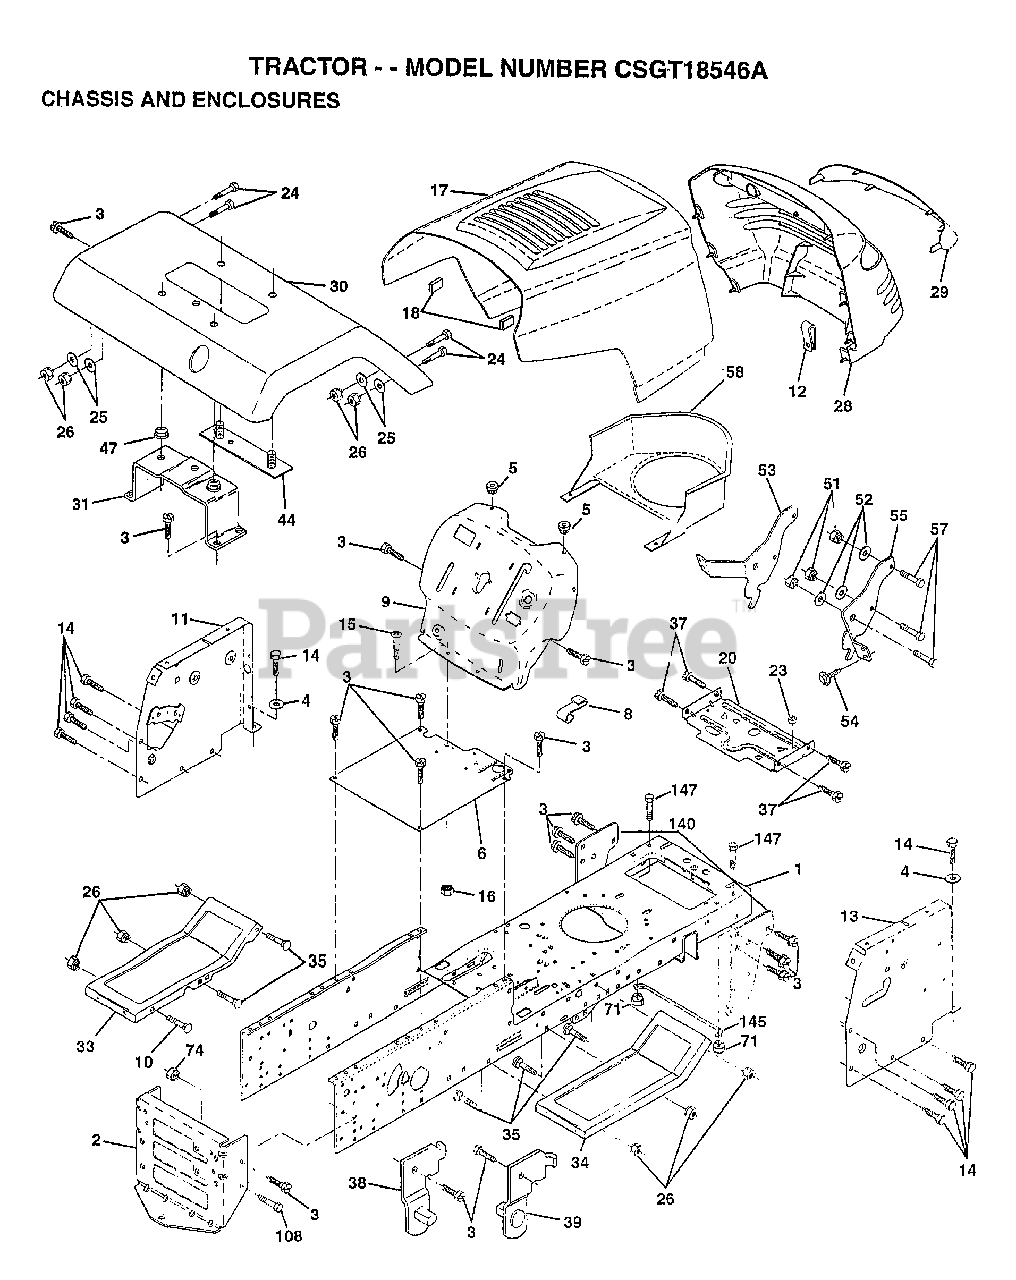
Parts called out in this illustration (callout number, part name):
1	CHASSIS ASM
3	SCREW
4	WASHER
5	BUMPER-HOOD/DASH
6	SADDLE
8	"CLIP,INSULATOR"
9	DASH SILKSCREEN
11	PANEL ASM DASH LH
12	CLIP.TINNERMAN
13	PANEL ASM DASH RH
14	SCREW LT
15	SCREW
17	"HOOD W/TRIM,MS428"
20	"PLATE-MTG,BATT/FU"
24	BOLT
25	WASHER
26	NUT
28	GRILLE-MS428
29	LENS GRILLE
30	"FENDER WS,FTK"
31	BRKT.ASM.FENDER
33	FOOTREST PNT LH
34	FOOTREST.RH.LT/GT
35	BOLT
37	SCREW LT
38	BRACKET ASM LH
39	BRACKET ASM RH
44	STRAP ASM FENDER
47	NUT-PUSH YT
51	NUT
52	WASHER
53	BRACKET.GRILLE.LH
55	BRACKET.GRILLE.RH
58	DUCT.AIR.B&S.18HP
140	BRKT SUSPENSION
145	"ROD POVOT,CHASSIS"
147	BOLT LT
